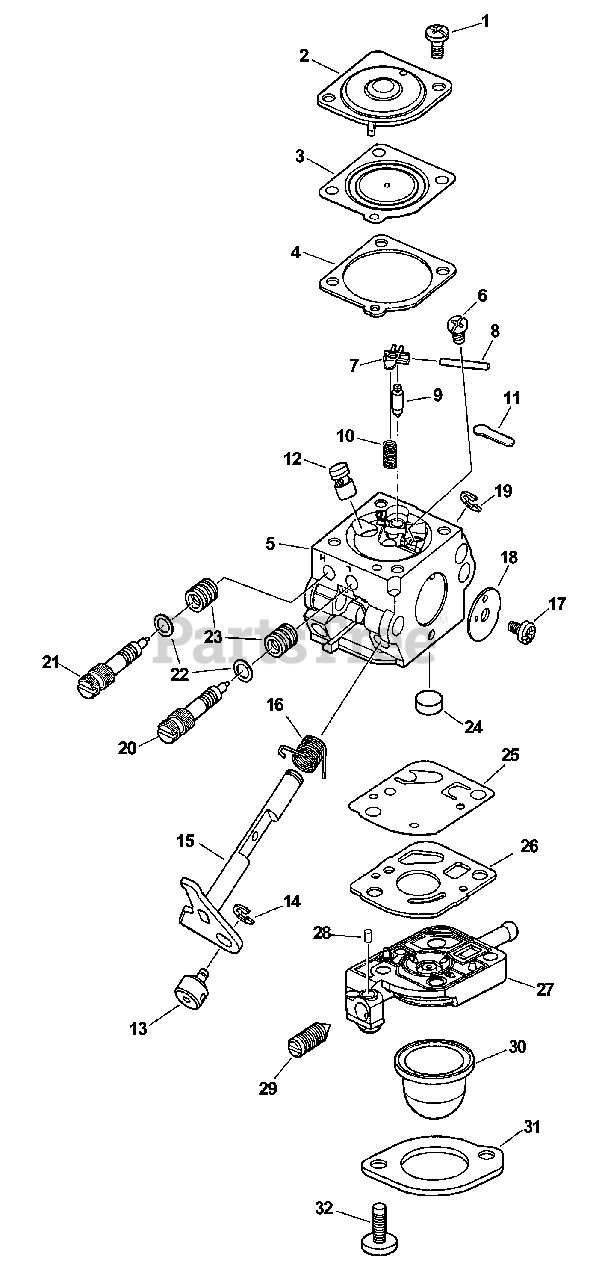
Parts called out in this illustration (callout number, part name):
2	COVER, METERING
3	DIAPHRAGM, METERING
4	GASKET, METERING
5	BODY, CARBURETOR
6	SCREW, METERING LEVER PIN
7	LEVER, METERING
8	PIN, METERING LEVER
9	VALVE, INLET NEEDLE
10	SPRING, METERING LEVER
11	PLUG, WELCH
12	NOZZLE, CHECK VALVE
14	RING, RETAINING
15	SHAFT, THROTTLE
16	SPRING, RETURN
18	VALVE, THROTTLE
19	RING, RETAINING
20	NEEDLE - LOW SPEED
21	NEEDLE - HIGH SPEED
24	STRAINER
25	DIAPHRAGM, PURGE
26	GASKET, PURGE
27	BASE, PURGE
28	PIECE, FRICTION
29	SCREW, IDLE ADJUST
30	BULB, PURGE
31	RETAINER, PURGE BULB
32	SCREW, RETAINER
